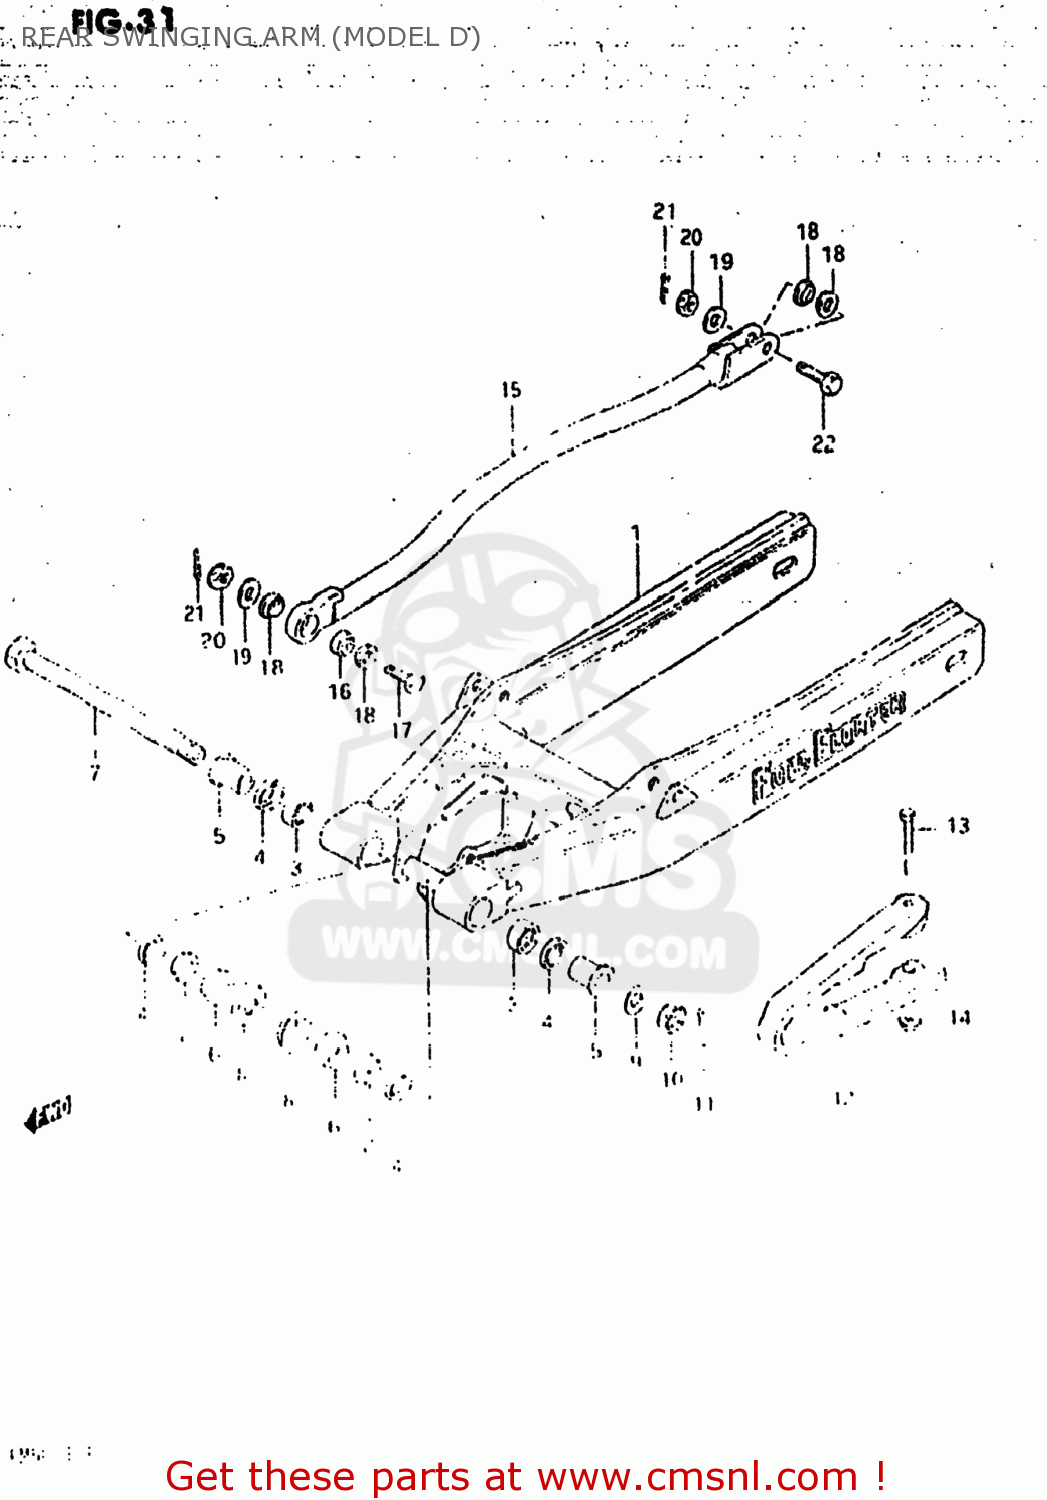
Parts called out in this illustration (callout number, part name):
1	SWING ARM ASSEMBLY,REAR
2	BUSHING,REAR SWING ARM PIVOT
3	BEARING(20X27X20)
4	OIL SEAL
5	SPACER,RR SWGARM PIVOT
6	SPACER,RR SWGARM PIVOT INNER
7	SHAFT,RR SWINGINGARM PIVOT
8	COVER,RR SWGARM DUST SEAL
9	WASHER
10	NUT 14MM
11	COTTER PIN
12	BUFFER,CHAIN TOUCH DEFENSE
13	BOLT(6X70)
14	NUT
15	TORQUE LINK SET,RR
16	SPHERICAL BEARING,TORQUE
17	BOLT 8X28
18	19
19	WASHER
20	NUT 8MM
21	PIN 20X20
22	BOLT 8X29.5
